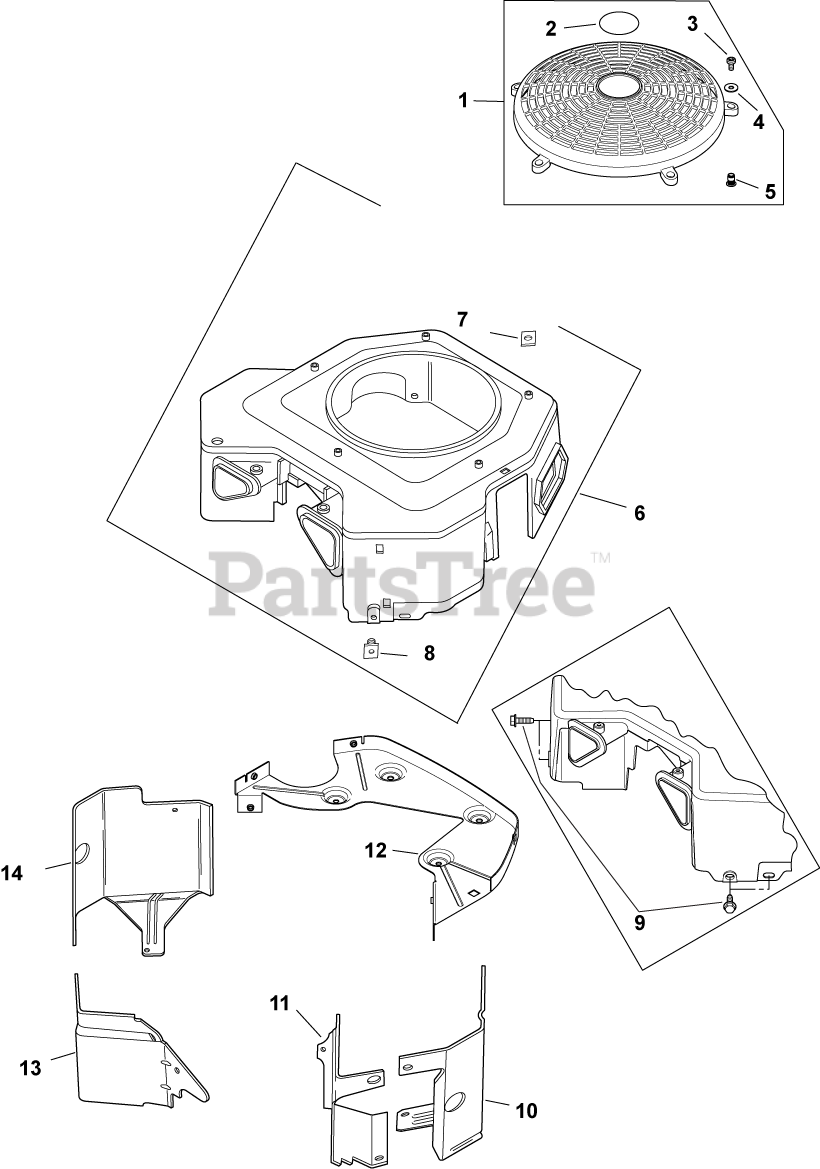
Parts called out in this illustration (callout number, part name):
1	KIT, FIXED GUARD
2	DECAL, GRASS SCREEN USE 24 113 499-S
3	SCREW, SEMS
4	WASHER, FLAT 7/32"
5	INSERT, THREADED USE 25 332 19-S
6	KIT, BLOWER HOUSING ASSY-(#24027492S)
6	KIT, BLOWER HOUSING
9	SCREW,FLG THD FRM M6X1.0X16-(#25086397S)
10	KIT, CYL BAFFEL #2 SIDE
11	BAFFLE, VALLEY #2 CYLINDER
12	KIT, BACKING PLATE
13	BAFFLE, VALLEY #1 CYLINDER
14	KIT, CYL BAFFEL #1 SIDE
M-545010-S	SCREW, FLG THD FRM M5X.8X10
